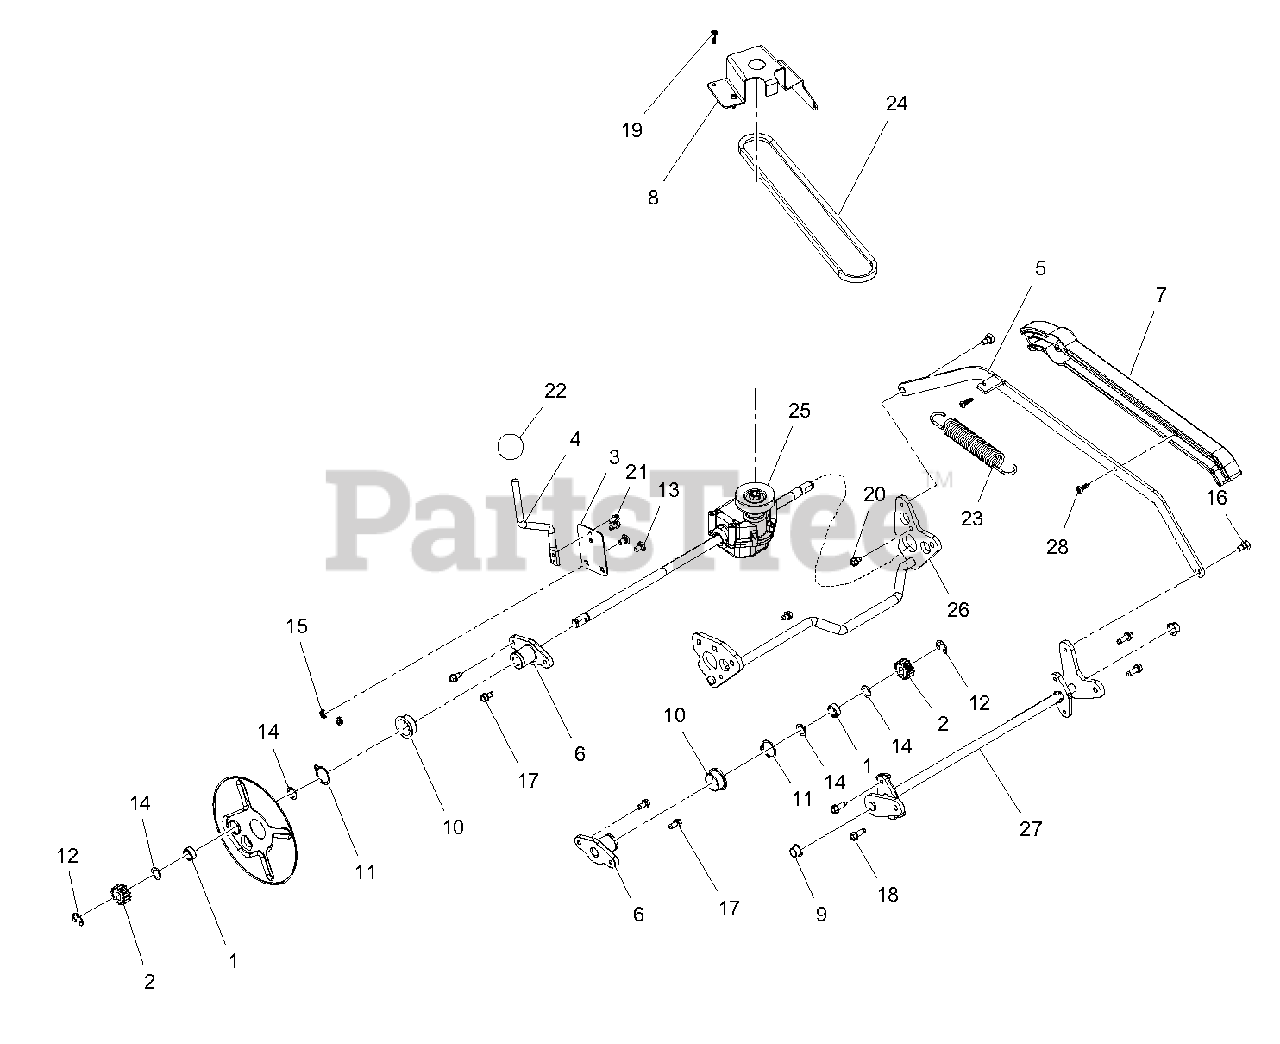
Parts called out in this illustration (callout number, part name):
1	SPCR, PM .500ID X .750D X .321
2	GEAR, PINION, LM WHEEL DRIVE
3	PLATE, HOC SPRING
4	LEVER, HOC ADJUST
5	LINK, HOC CONNECT
6	HUB, LM REAR AXLE
7	COVER, LINK ROD
8	GUIDE, BELT TRANSMISSION
9	BSHG, SPLIT NYLON
10	BSHG, FLANGE 1.0x1.25x.50x1.375
11	RG-RTNG-EXT 1.00X.042
12	RG-RTNG-EXT .500X.042 €
13	@BLT-RDHDSQNK .25-20X.50 G5 Y
14	WASHER-FLAT-STL, .500 X .750 X .020
15	@NUT-LK-CTR-JAM .25-20 YWZC
16	BOLT, SHLDR .320X.210X.25-20 SELF-TAPPING
17	SCR-TAP .25-20X.50 HWH TR YWZ
18	SCR-TAP .25-20X.75 HWH TR YWZ
19	SCR-TAP #10-14X.75 PLASTITE BLZC
20	SCR-TAP .25-20X.37 HWH YWZ TR
21	SCR-TAP 12-24X.50 HWH TR YWZC
22	KNOW, BALL -BLACK 1.47" .375-16
23	SPRG, EXTENSION
25	TRANSAXLE, AUTOMATIC, LM, 9:1
26	WLDMT, LM REAR AXLE
27	WLDMT, LM FRONT AXLE
28	SCR-TAP #12-14X.75 PLASTITE BLZC
